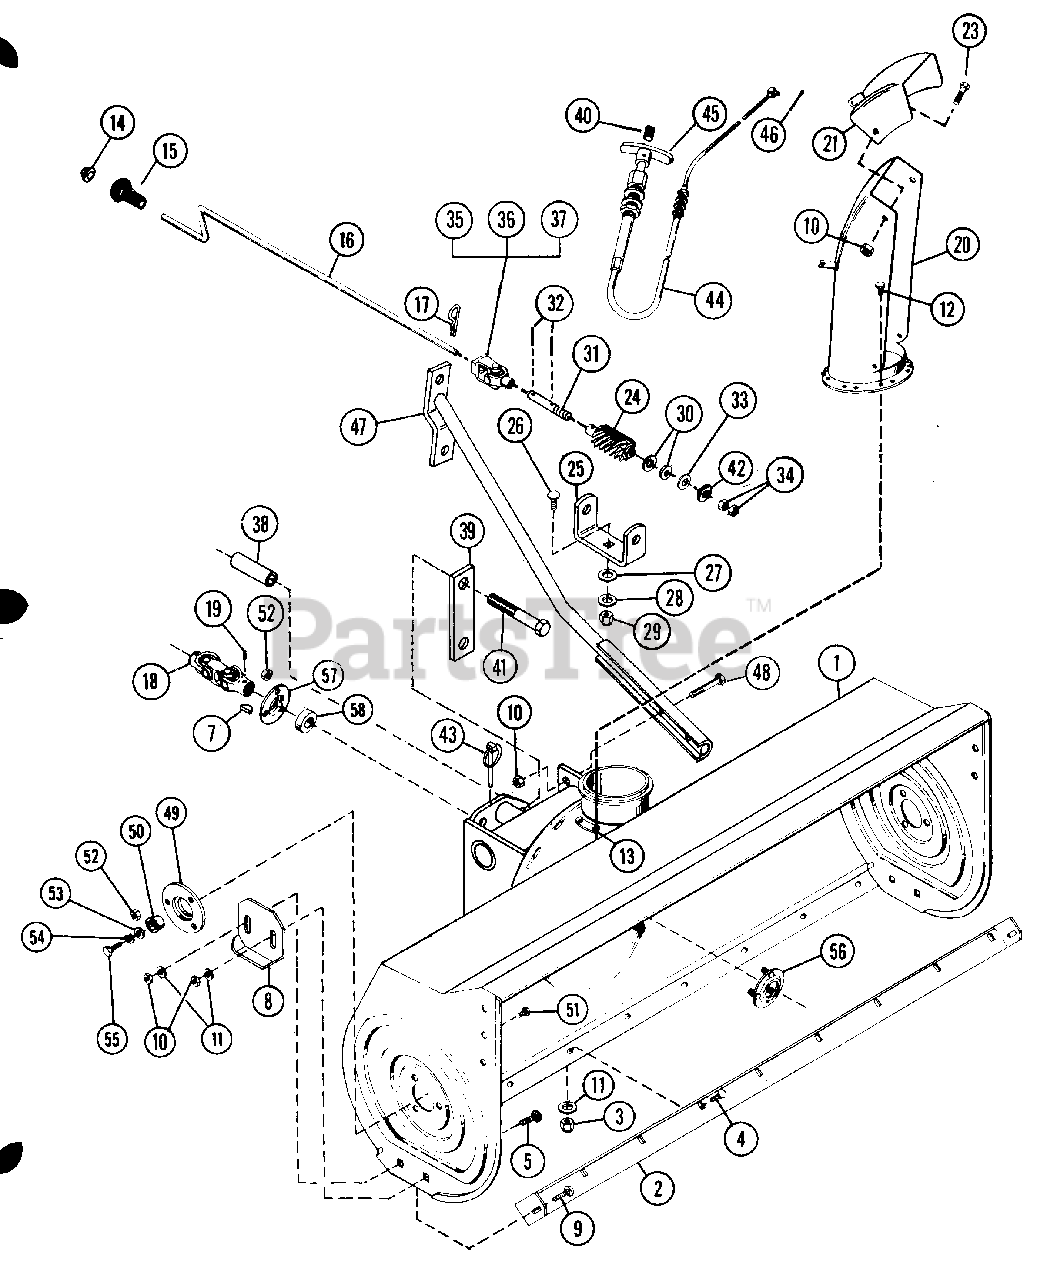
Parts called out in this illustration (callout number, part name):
1	32" SNO THRO HOUSING
2	SCRAPER BLADE
3	NUT, LOCK 5/16-18
4	BOLT 5/16-18X.625 RD HD SQ NK
5	BOLT, CARRIAGE 3/8-16X.75
7	KEY, WOODRUFF 3/16X7/8 HRD #11
8	RUNNER, SKID SHOE
9	BOLT, 3/8-16X1.00 RD HD SQ NK
10	NUT, LOCK 3/8-16
11	WASHER, FLAT .406X.812X.065
12	SCREW, TAPTITE #10-24X.375
13	CLAMP, CHUTE
14	CAP
15	KNOB
16	CRANK, CHUTE CONTROL
17	HAIR PIN, INTERNAL
18	JOINT ASSEMBLY
19	SCREW, SET 3/8-16X.38 SKHCUP
20	DISCHARGE CHUTE
21	CHUTE DEFLECTOR
23	BOLT, HEX 3/8-16X.75
24	WORM GEAR, L. H.
25	WORM CLEVIS
26	BOLT, CARRIAGE 5/16-18X.75
27	WASHER, LOCK 3/8 EXT. TH. TYA
28	WASHER, LOCK SPECIAL 5/16 I.D.
29	NUT, HEX 5/16-18
30	WASHER, PLASTIC .390X.875X.0
31	WORM SHAFT
32	PIN, SPRING .125X.750
33	WASHER, .390X.875X7 GA.
34	NUT, JAM 3/8-16 HEX
35	UNIVERSAL HALF
36	BLOCK, UNIVERSAL
37	PIN, SPRING .187X1.00
38	SPACER
39	STRAP, LOCKING
40	SCREW, MACHINE 10-32X.50
41	BOLT, HEX 1/2-13X4.50
42	WAVE WASHER
43	PIN, SELF-LOCKING
44	CABLE, CONTROL
45	HANDLE, TEE
46	PIN, COTTER .09X.75
47	CRANK SUPPORT
48	BOLT, HEX 3/8-16X2.00
49	BEARING SUPPORT
50	BUSHING, FLANGE
51	BOLT, RIB NECK 1/4-20X.50
52	NUT, LOCK 1/4-20
53	WASHER, FLAT .515X1.441X.1
54	WASHER, LOCK 3/8 SP. HEAVY
55	BOLT, HEX 1/2-13X1.00
56	BEARING, FLANGE
57	BEARING, FLANGE
58	BEARING, BALL
NS	DECAL, GRAVELY LOGO
NS	DECAL, DANGER FOOT
NS	DECAL, AMERICA
NS	DECAL, DANGER HAND
NS	DECAL, CHUTE
NS	DECAL, DEFLECTOR
